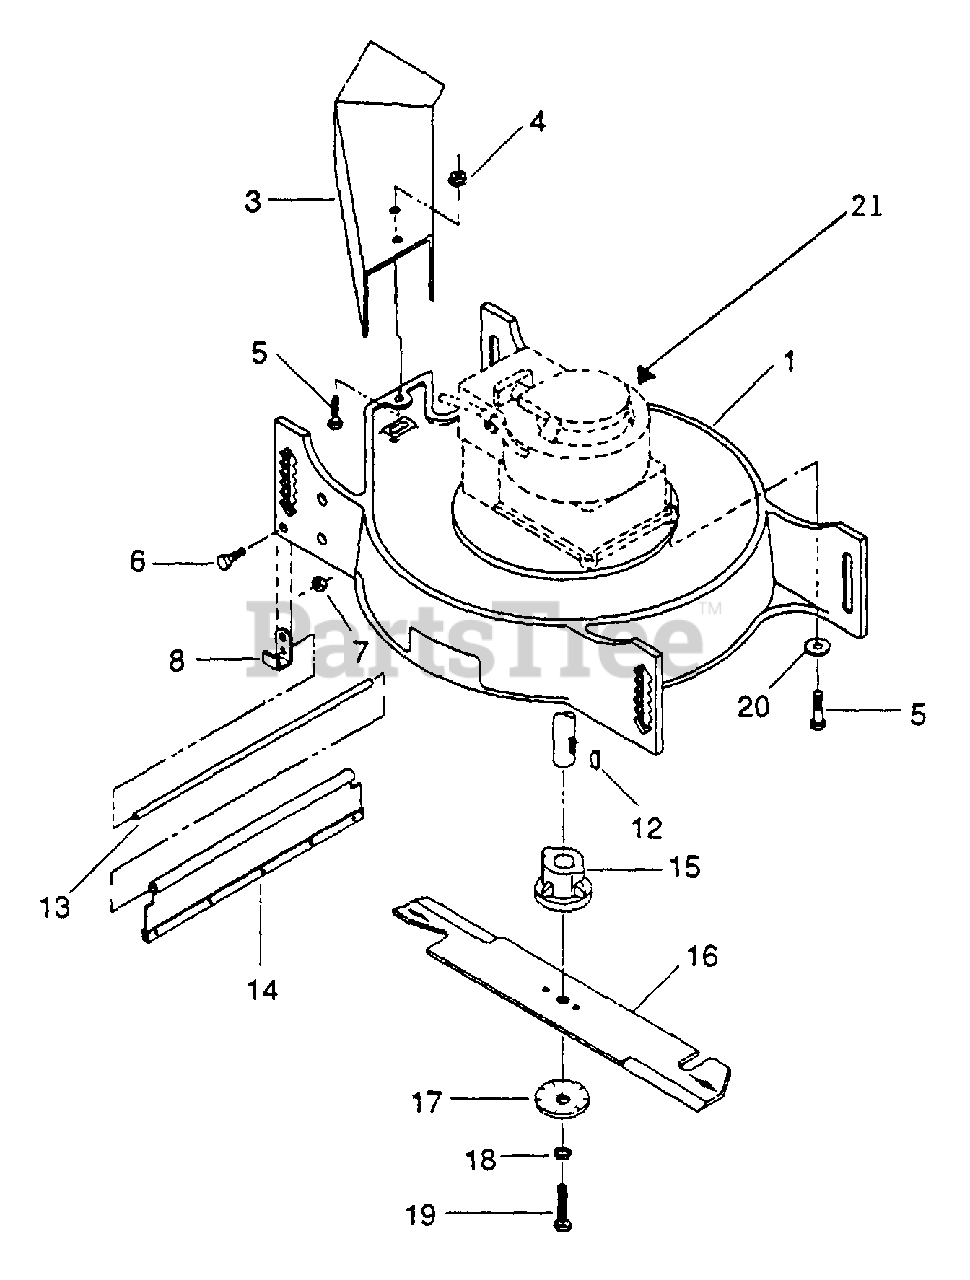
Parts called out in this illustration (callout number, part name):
1	DECK
3	GRASS CHUTE
4	NUT 5/16
5	SCREW HEX 5/16×3/4
6	SCREW - 5/16×1-1/4" -- HEX CAP
7	NUT, 5/16 NYLOC
8	SAFETY SHIELD CLIP
12	KEY, WOODRUFF - 6
13	DRAG SHIELD ROD
14	DRAG SHIELD ASSY
15	25 MM BLADE DRIVER
16	BLADE - 21"
17	CUPPED WASHER
18	LOCKWASHER - 3/8"
19	SCREW 3/8"×3/4
20	5/16" DISC SPRING
21	ENGINE - M14V-B1ZO
